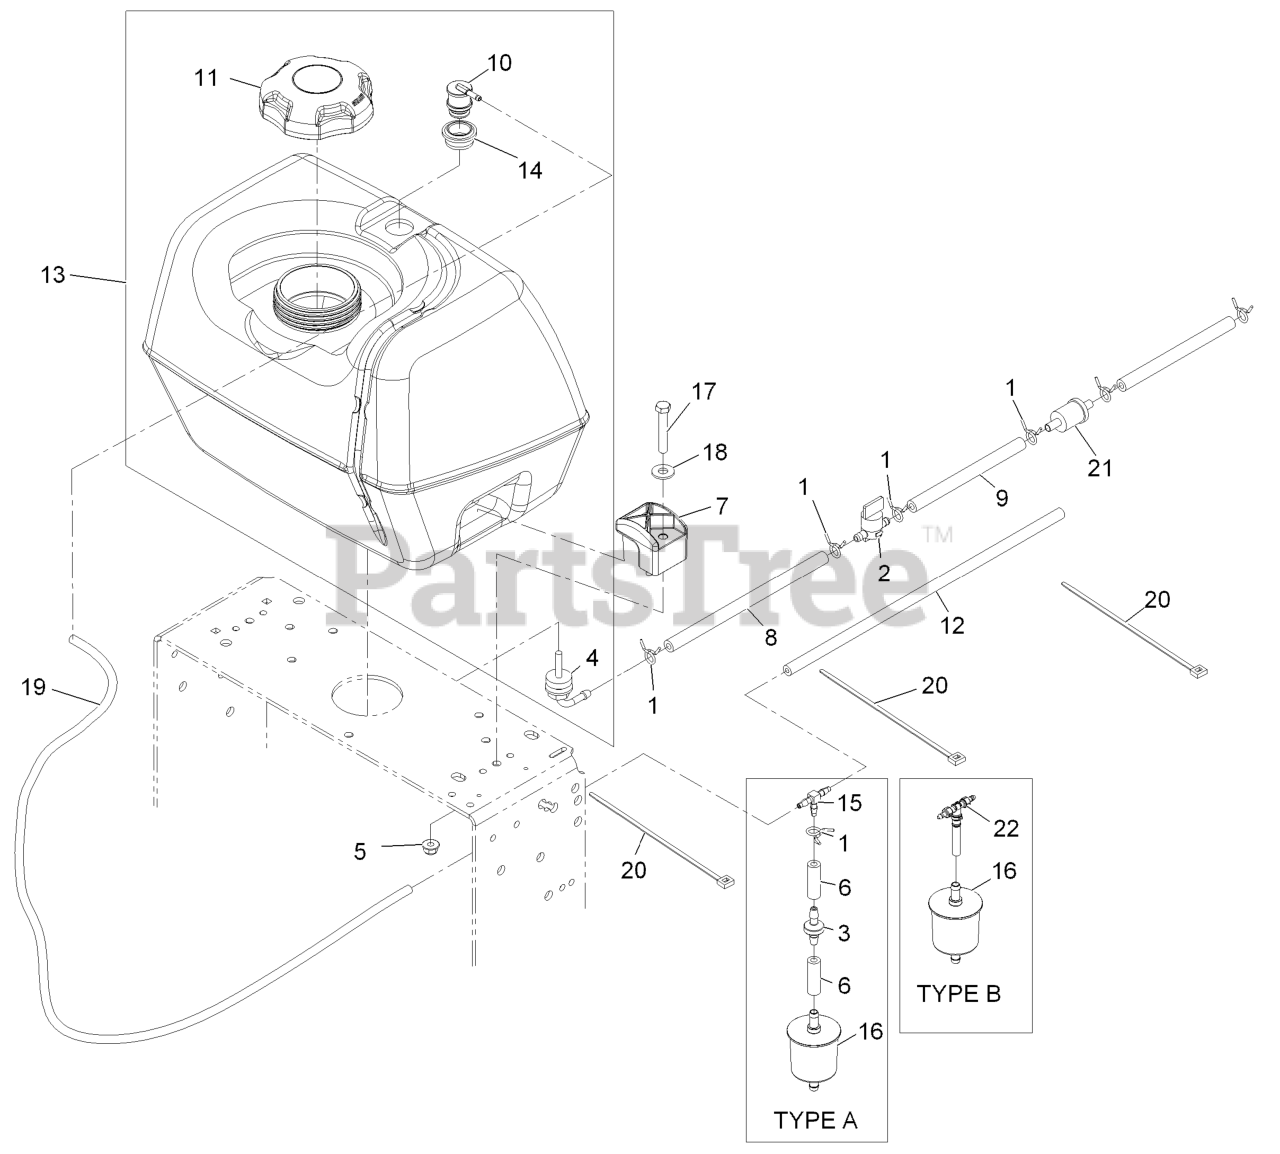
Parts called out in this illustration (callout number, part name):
1	CLAMP-HOSE
2	VALVE-FUEL
3	VALVE-CHECK, FUEL
4	FITTING-FUEL, BULKHEAD
5	NUT-HF, NI
6	HOSE-FUEL
8	HOSE-FUEL
9	HOSE-FUEL
12	HOSE-FUEL
14	GROMMET
15	FITTING-TEE
16	FILTER-FUEL
17	SCREW-HH
18	WASHER-FLAT
19	HOSE-EMISSIONS
20	TIE-PLASTIC
21	Pn 41019-1055 Filter W/6in Fuel Line
22	TEE AND CHECK
